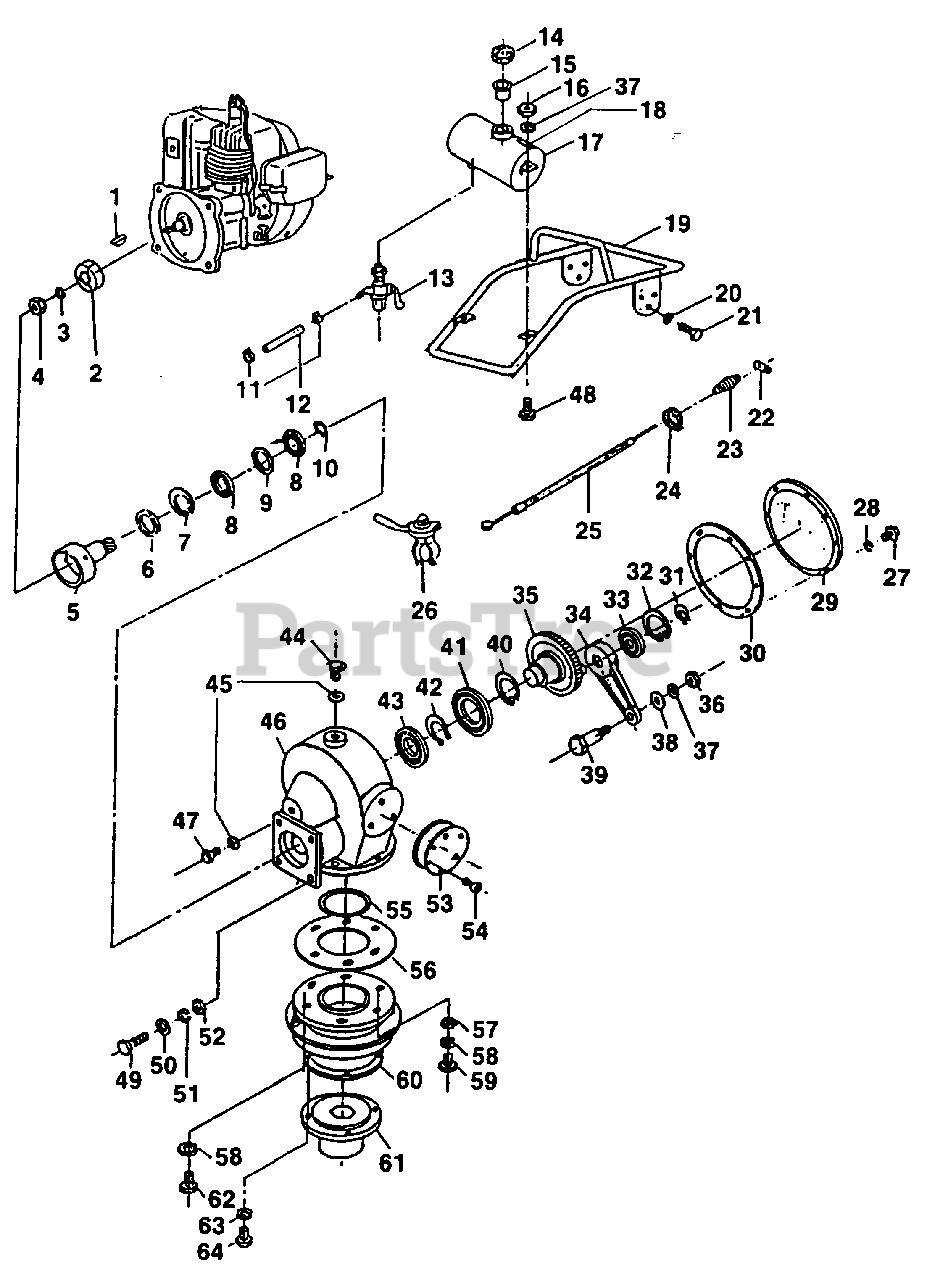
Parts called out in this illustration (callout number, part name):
2	CLUTCH- Centrifugal
3	WASHER- Spring m12
4	NUT- Hex m12 x 1.25
5	DRUM- Piston Gear
6	SEAL- Oil
7	RING- Snap (H-52)
10	RING- Snap (S-25)
11	CLAMP- Tube
12	HOSE- Rubber
13	VALVE- Fuel
14	CAP- Fuel Tank
15	FILTER- Fuel Tank
16	NUT- Hex m8
17	TANK- Fuel
18	CAUTION DECAL
20	WASHER- Spring m10
21	BOLT- Hex m10 x 20
22	END- Screw
23	SPRING- Return
24	BAND- Wire
25	WIRE- (Throttle)
26	LEVER- Throttle
27	BOLT- Hex m6 x 15
28	WASHER- Spring
29	COVER- Crankcase
31	RING-Snap (S-20)
32	RING- Snap (H-47)
34	ROD- Connecting
35	GEAR- Crank
36	NUT- Nylon m8
37	WASHER- Spring m8
38	WASHER- Plate
39	PIN- Roll
40	RING- Snap
42	RING- Snap
44	BOLT- Oil Flange m14
45	WASHER- Plate
46	CRANKCASE
47	BOLT- Oil Flange m6 x 15
48	BOLT- Hex m8 x 20
49	BOLT- Hex m10 x 40
50	WASHER- Plate m10
51	WASHER- Spring m10
52	NUT- Nylon m10
53	ABSORBER- Shock
54	BOLT- Hex
57	NUT- Nylon m8
58	WASHER- Spring m8
59	BOLT- hex
60	GUIDE- Cylinder
61	GUIDE- Cylinder
62	BOLT- Hex m8 x 25
63	WASHER- Spring
64	BOLT- Hex
